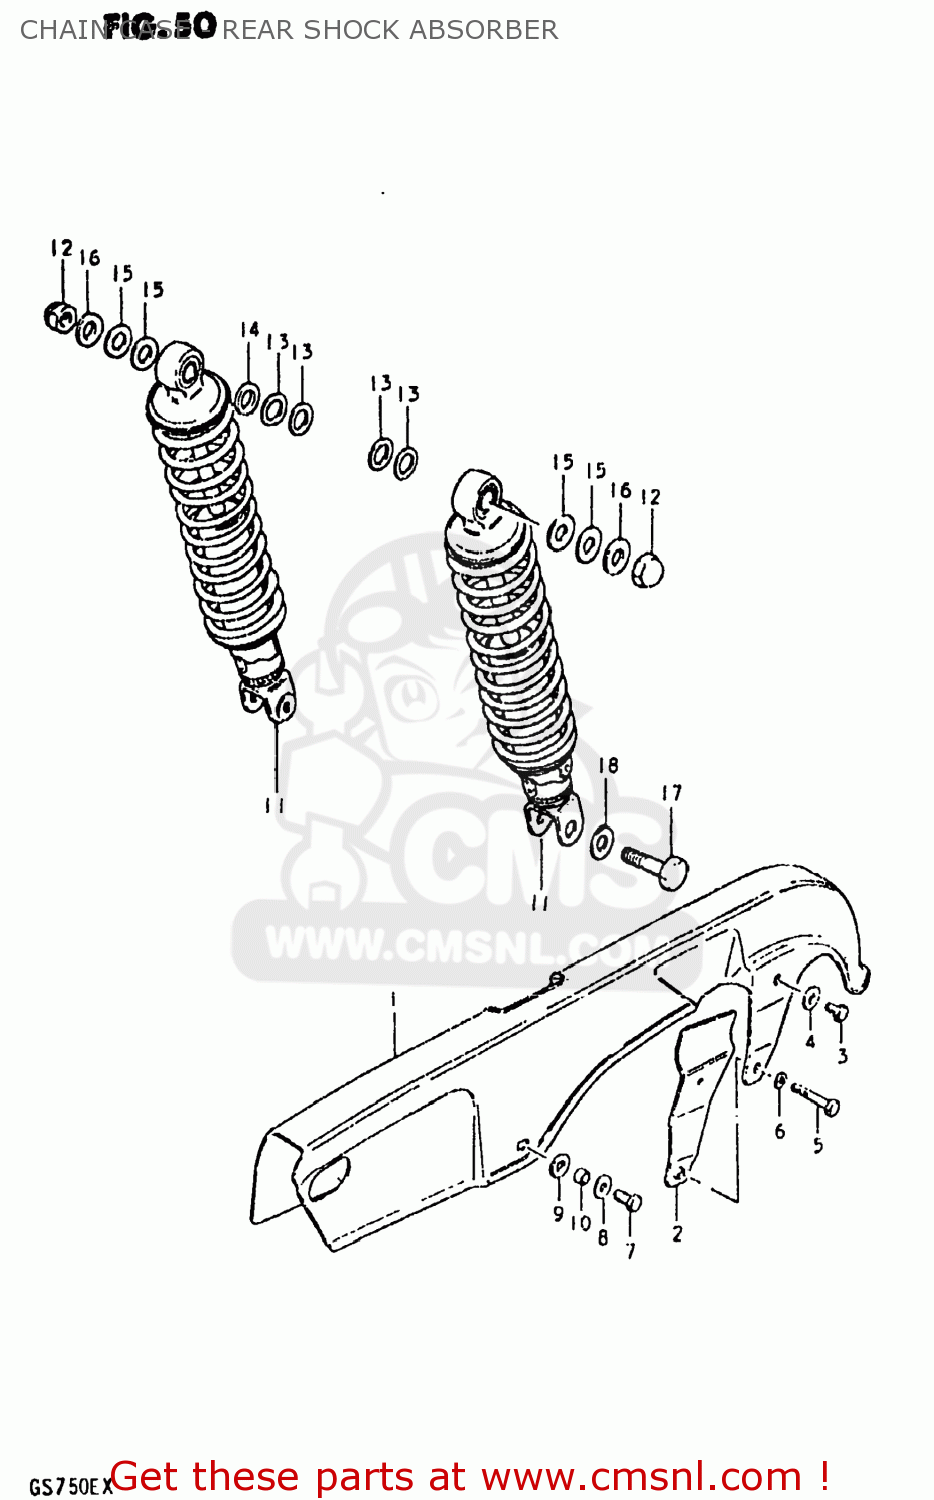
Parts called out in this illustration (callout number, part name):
1	CASE,CHAIN
2	REINFORCEMENT,CHAIN CASE
3	BOLT(6X8)
4	WASHER
5	BOLT
6	LOCK WASHER
7	BOLT
8	WASHER(6.5X18X1)
9	CUSHION
10	SPACER (6.1X8X5.2)
11	ABSORBER ASSEMBLY,REAR SHOCK
12	NUT, LOWER LH
13	WASHER
14	WASHER (12.5X24X3.2)
15	WASHER
16	WASHER(10.5X24X3.2)
17	BOLT(10X36)
18	WASHER
